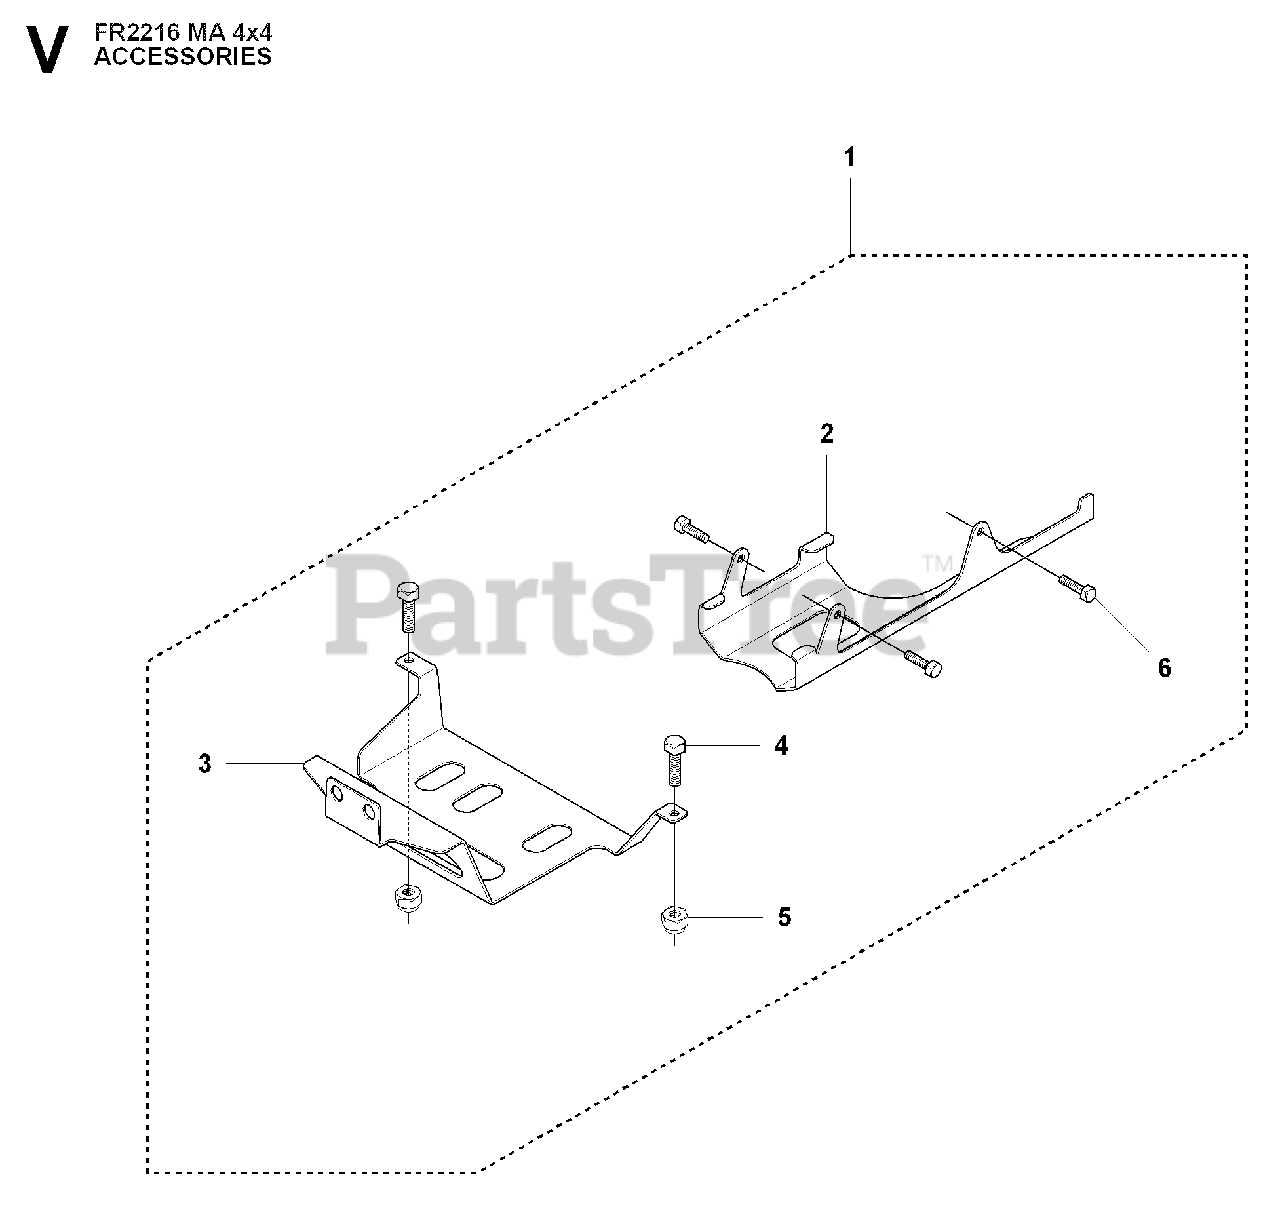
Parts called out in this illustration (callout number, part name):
3	RP PROTECTION PLATE REAR
5	LOCKNUT M8
6	BOLT FLANGE - M8X16
